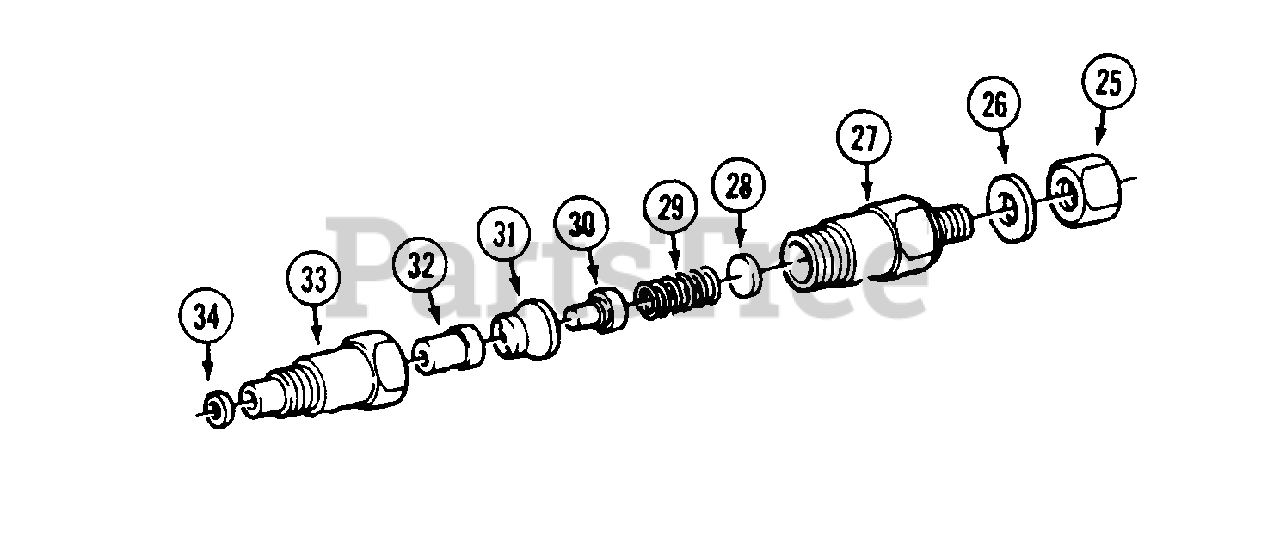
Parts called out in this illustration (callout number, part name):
25	NUT
26	WASHER
27	BODY
28	SHIM - 0.90mm
29	SPRING
30	PIN
31	SPACER
32	NOZZLE
33	NUT
